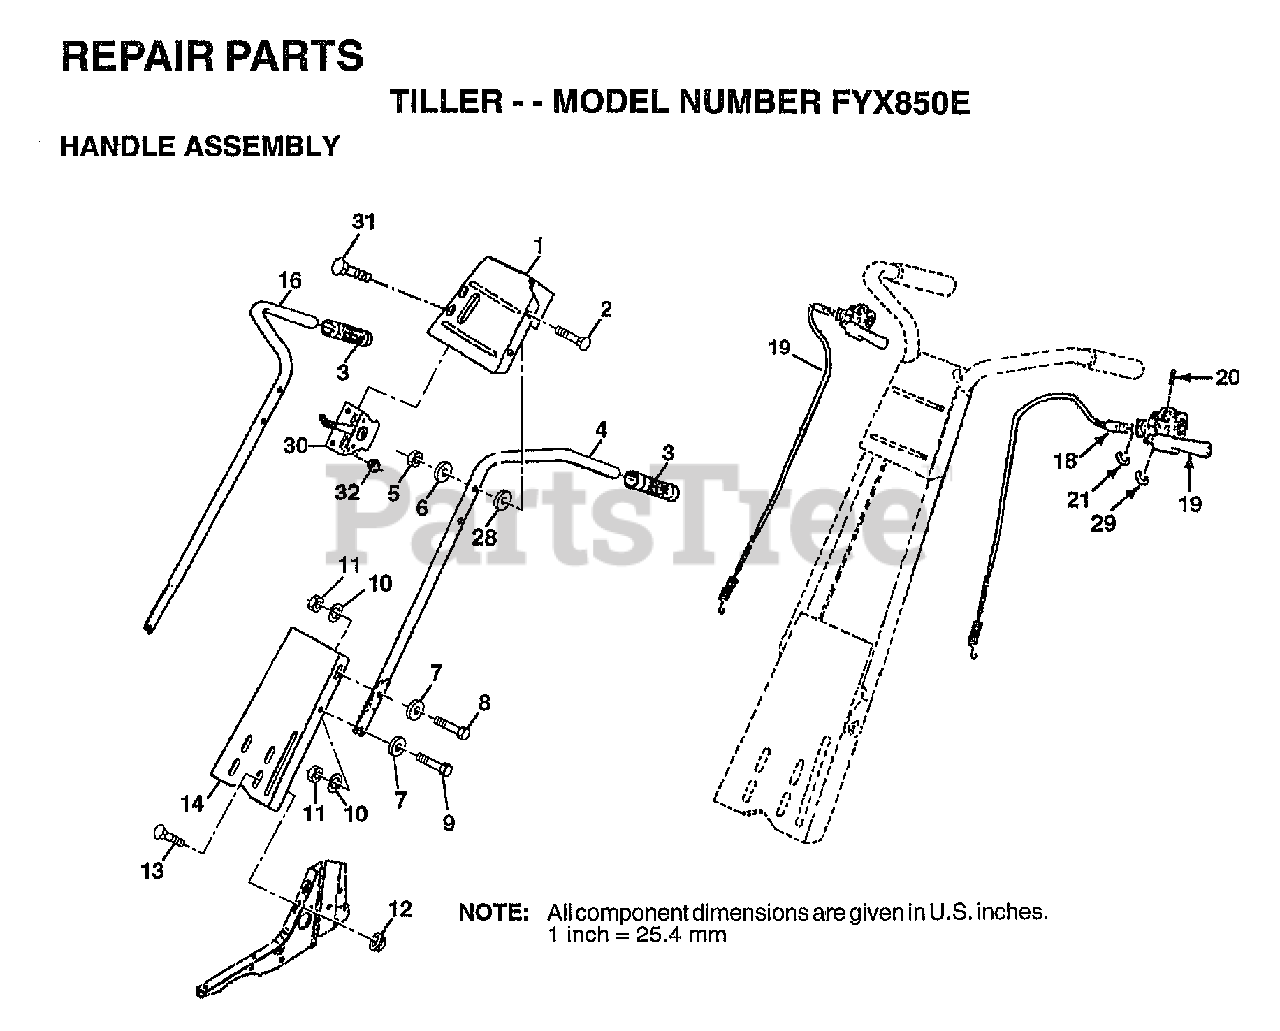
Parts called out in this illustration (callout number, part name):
1	BRACKET.HANDLE
2	BOLT
4	HANDLE.LH
6	WASHER
7	WASHER
9	BOLT
10	LOCKWASHER
11	NUT.HEX.5/16-18
12	NUT
13	BOLT
14	"PANEL, HANDLE"
16	HANDLE.RH.DOUBLE.BEND
18	CABL.CLUTCH.49.88
19	LEVER CONTRL TINE
20	"PIN PIVOT,GROOVED"
21	E-RING
28	WASHER
29	RETAINER RING
30	CONTROL THROTTLE
31	SCREW.PNHD.10-24
